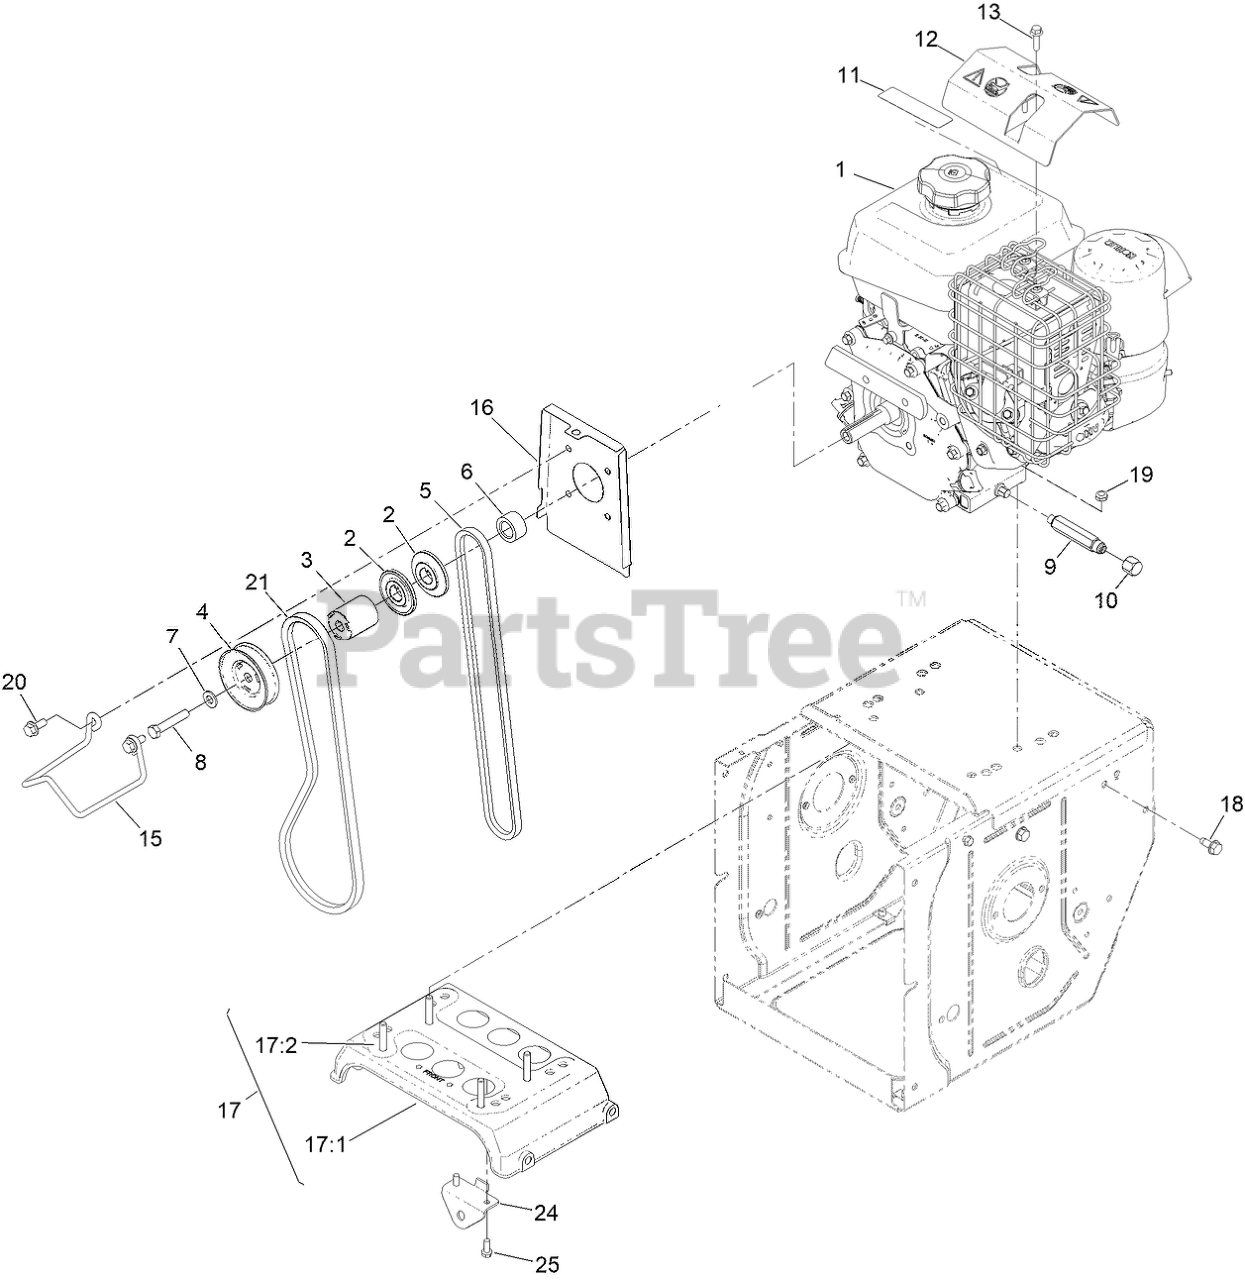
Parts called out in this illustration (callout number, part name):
2	SHEAVE-TRACTION
3	SPACER-PULLEY
4	PULLEY-IMPELLER
5	BELT,3L P21 DRIVE
6	SPACER
7	WASHER-FLAT
8	SCREW-HH
9	ADAPTER
11	DECAL-ARRESTOR, SPARK
12	DEFLECTOR-DEBRIS, MUFFLER
13	SCREW-HHF
15	GUIDE-BELT
16	COVER-CRANK
17	ENGINE PLATE ASM (G250)
17:1	PLATE-ENGINE
17:2	STUD-PRESS 95/16-18 X 1.625)
18	SCREW-HWHTF
19	NUT-HEX
20	SCREW-HH
21	V-BELT
24	BRACKET-CONTROL, TRACTION
25	SCREW-HWH
